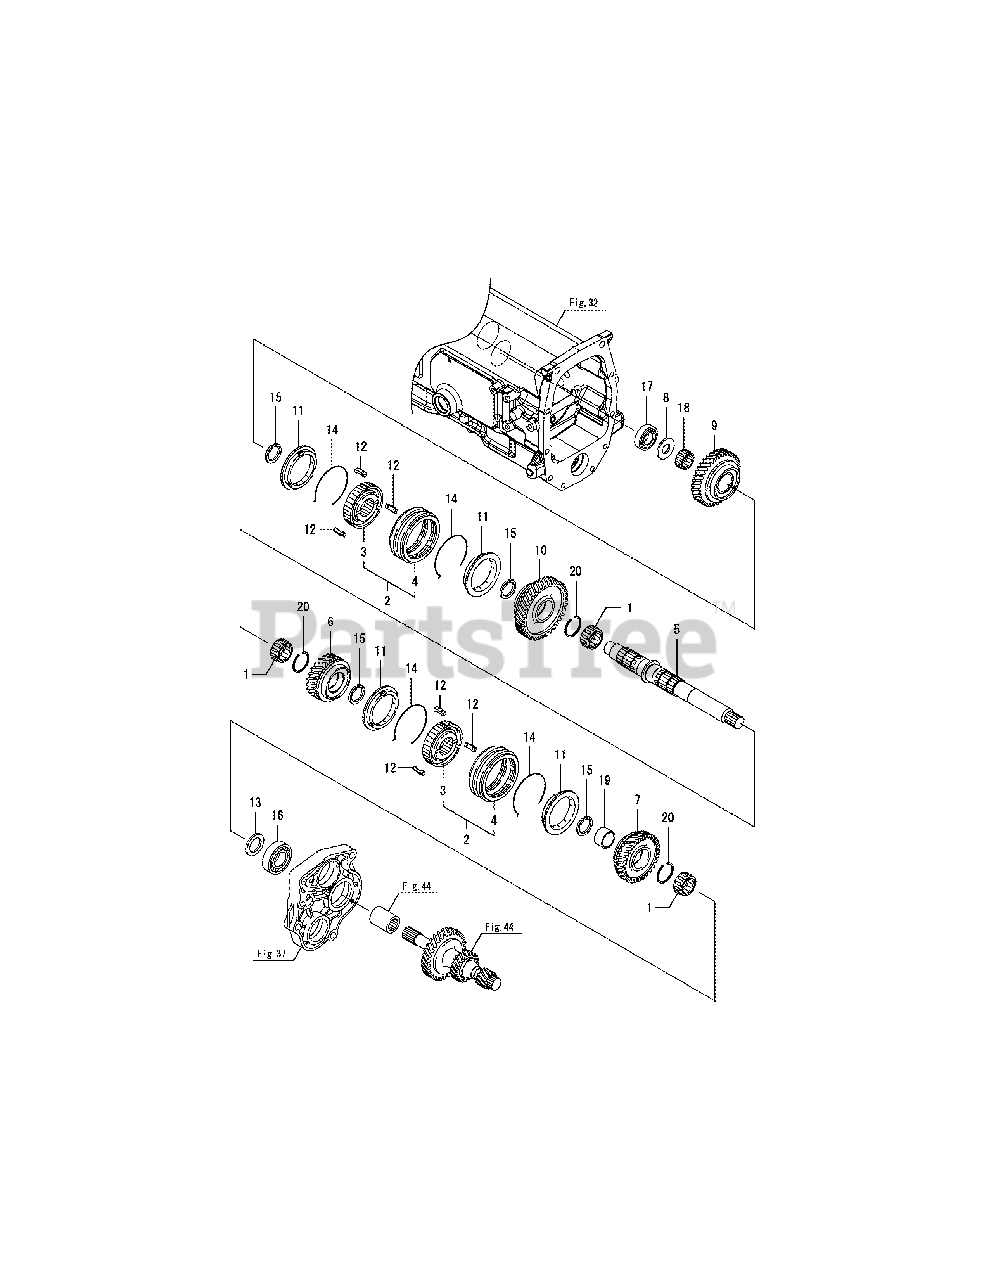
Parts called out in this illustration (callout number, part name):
1	NEEDLE BEARING
2	HUB ASSY, SYNCHRO
6	GEAR 39, DRIVEN
7	GEAR 44, DRIVEN
8	WASHER 20X43X2.5
9	GEAR 49, DRIVEN
10	GEAR 53, DRIVEN
11	SYNCHRONIZER RING
12	KEY A SYNCHRONIZER
13	WASHER 30.3X45X3
14	SPRING, SYNCHRONIZE
18	NEEDLE BEARING
19	COLLAR 30X35X20
